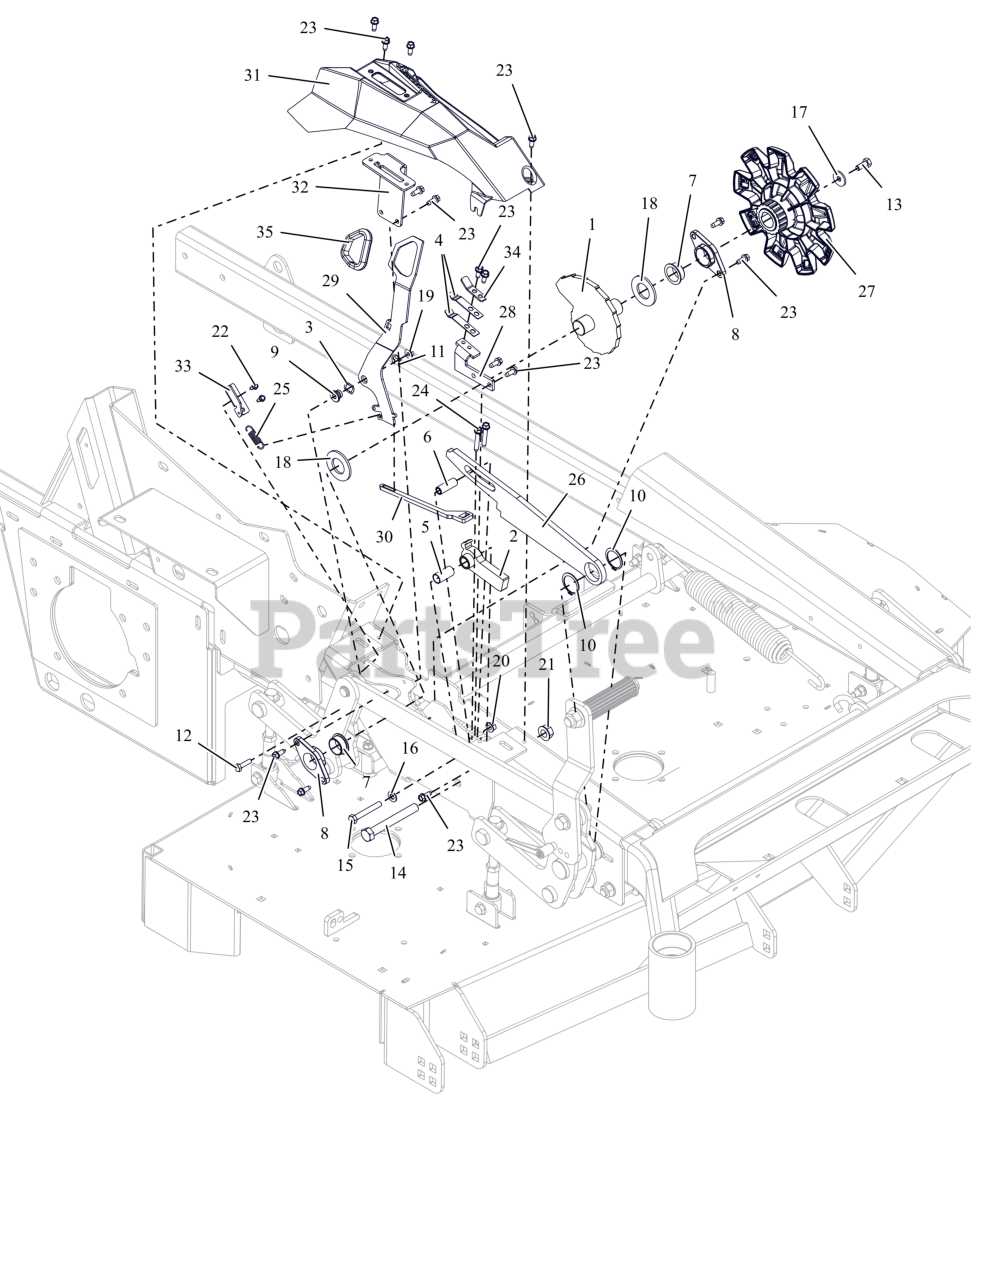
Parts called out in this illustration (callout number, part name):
1	WLDMT, HOC
2	WLDMT, TRANSPORT LOCK PAWL (BLACK)
3	WAVE WASHER .531X.781X.125FH
4	ARM, HOC DETENT
5	SPCR-SLV .531 X .625 X 1.25
6	SPCR, SLV .328 X .439 X 1.381
7	BSHG-FLG 1.0X1.125X.50X1.375 R
8	BSHG, 1.000X1.375X.650
9	BSHG FLANGED .270 X .500 X .468 X .75
10	RG-RET-EXT 1.25 X .050
11	RG-RTNG-EXT .500X.042 (E)
12	BLT,HEX .25-20X1.00 G5 ZCC
13	BLT,HEX .31-18X.75 G5 ZCC
14	BLT, HEX .50-13X4.00 G5 ZCC
15	BLT, HEX .31-18X2.25 G5 ZCC
16	WSHR,FLT .344X.688X.065 ZCC
17	WSHR,FLT .328X1.00X.094 ZCC
18	WSHR-FL-STL 1.062X2X0.134 ZCC
19	NUT-LK-CTR-FLG .25-20 ZC120
20	NUT,LK-CTR-FLG .31-18 GF ZCC
21	NUT-LK-CTR-FLG .500-13 GG ZCC
22	SCR,TAP #10-24X.50 HWH TR ZCC
23	SCR,TAP .25-20X.625 HWH ZCC
24	SCR-TAP .25-20X1.50 HWH ZCC
25	SG-TENS .063X.44X1.56
26	ARM, HOC LINK (BLACK)
27	WHEEL, HOC INDEX
28	BRKT, HOC DETENT MTG (BLACK)
29	LEVER, TRANSPORT LOCK (BLACK)
30	ARM, TRANSPORT LOCK (BLACK)
31	COVER, TRANSPORT LOCK
32	PLATE, TRANSPORT LOCK POSITION (BLACK)
33	BRKT, SPRG (BLACK)
34	TAB, REINFORCING (BLACK)
35	GROMMET 1.70ID X 2.0OD
